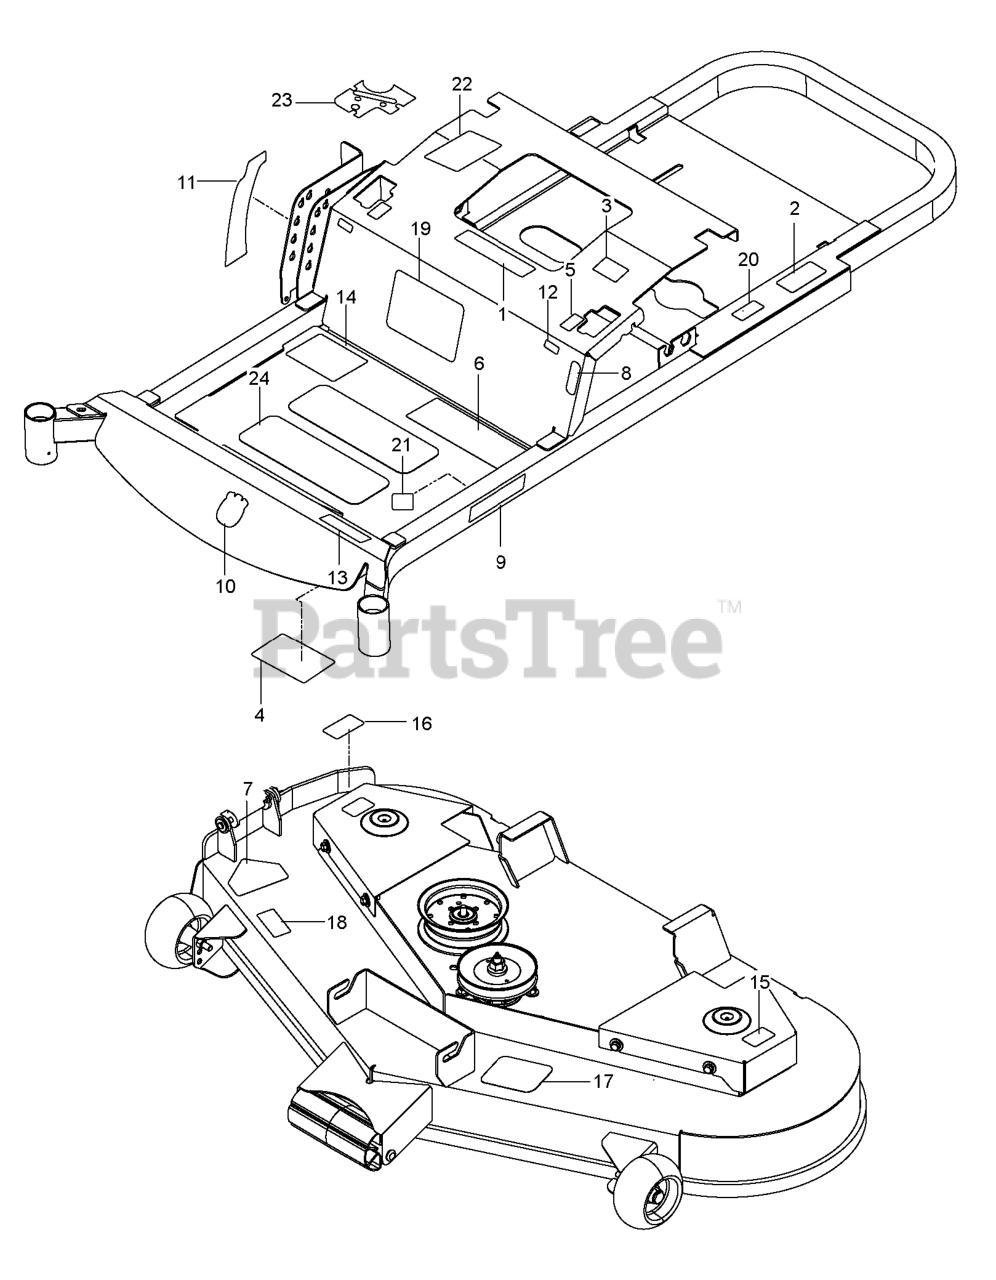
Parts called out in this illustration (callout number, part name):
1	EURO DECAL-BATTERY WARNIN6
2	DECAL, DO NOT TOW
3	DECAL, EXITING MOWER
4	DECAL, SERVICE
5	DECAL, MOTION CONTROL
6	DECAL, SAFETY WARNING
7	DECAL, CPSC
8	DECAL, PARK BRAKE
9	RP.DECAL.BADGE.170MM.TEXTLOGO
10	DECAL.AUGER.HUSQ.CROWN.SNOW
11	DECAL, DECK HEIGHT, HUSQ
12	DECAL, F.S.T.
13	DECAL MODEL EZ 4824TF
14	DECAL, WARNING
15	DECAL, NO STEP
16	DECAL, CAUTION
17	DECAL, BELT ROUTING
18	DECAL, EURO SEVERING
19	DECAL, START
20	DECAL, ECM, AUSTRALIA
21	DECAL 80 DBA
22	DECAL, CUSTOMER RESPNSIBILITY
23	DECAL, CTRL PANEL, HUSQ
24	ANTI-SKID PAD
